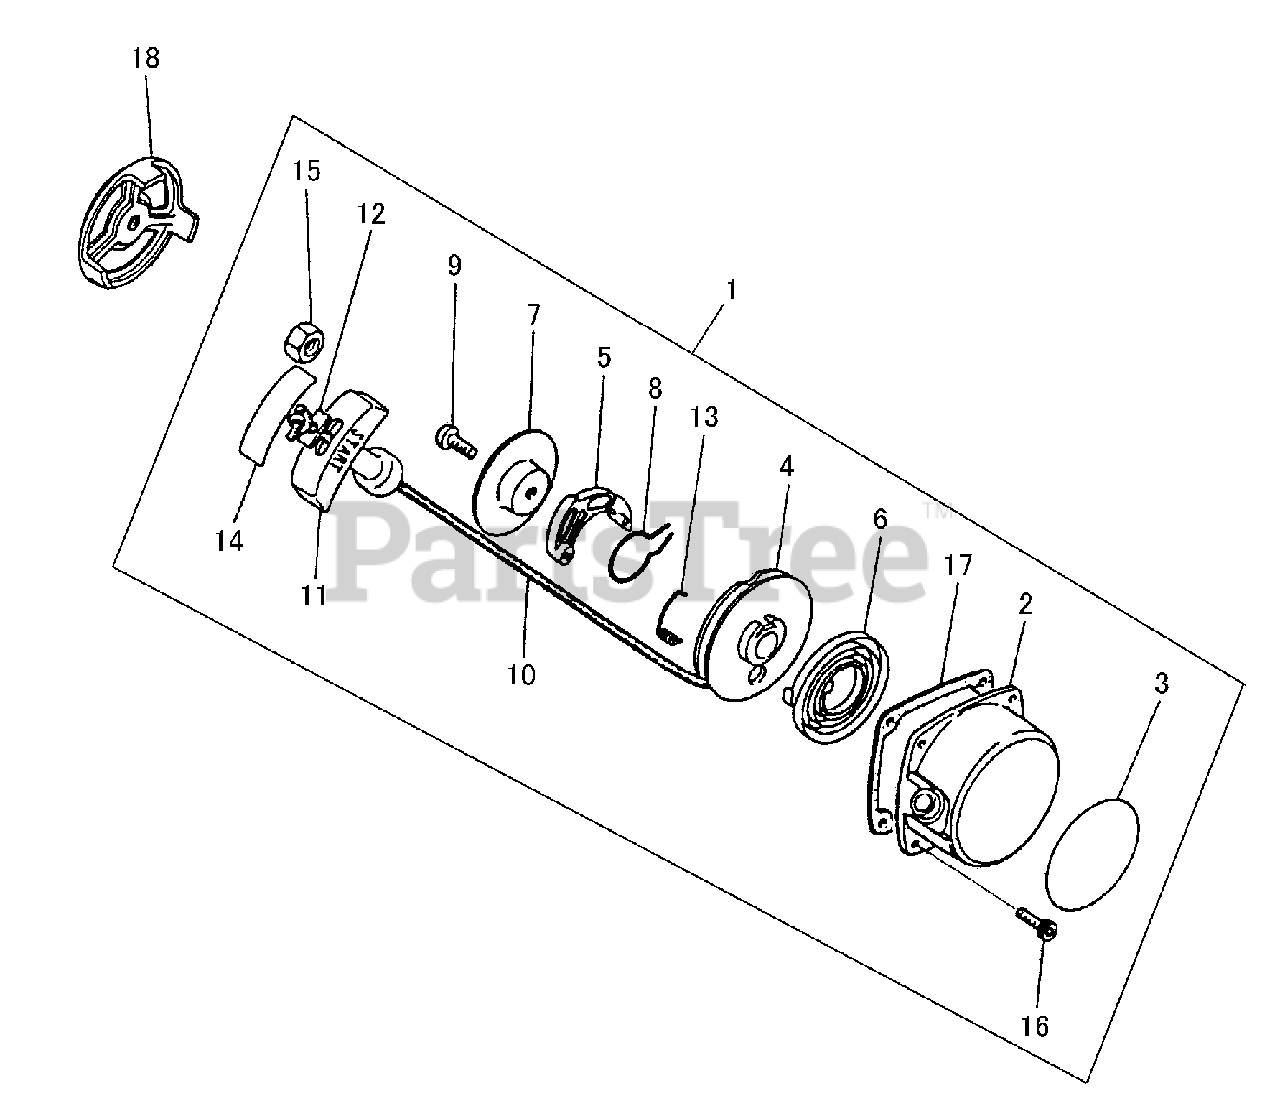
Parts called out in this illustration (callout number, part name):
1	STARTER ASSY, RECOIL
2	CASE, RECOIL STARTER
3	LABEL, TRADE
4	REEL, ROPE
5	RATCHET
6	SPRING, RECOIL
7	PLATE, FRICTION
8	SPRING, FRICTION
9	SCREW
10	ROPE, STARTER
11	GRIP, STARTER
12	RETAINER, ROPE
13	SPRING, RETURN
14	TAPE
15	NUT M8×H5
16	BOLT M4×16
17	GASKET
18	PULLEY, STARTER
